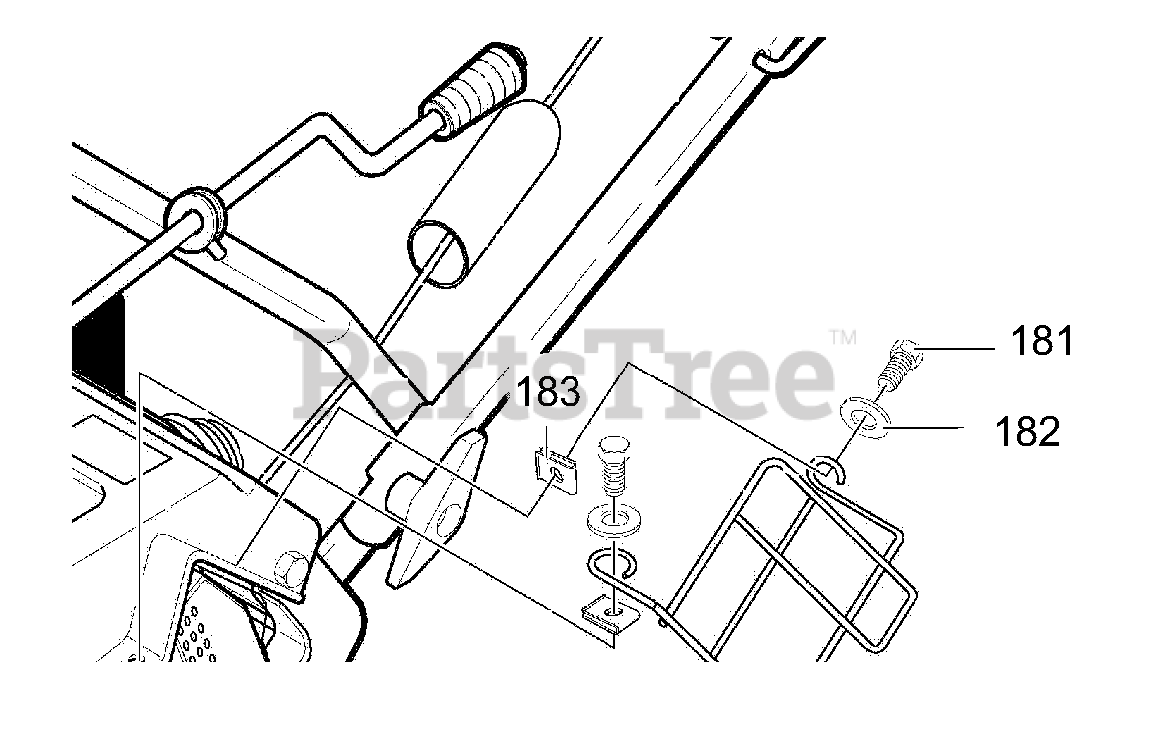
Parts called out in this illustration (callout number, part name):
180	GUARD, MUFFLER -EXPT
181	SCREW
182	WASHER, FLAT
